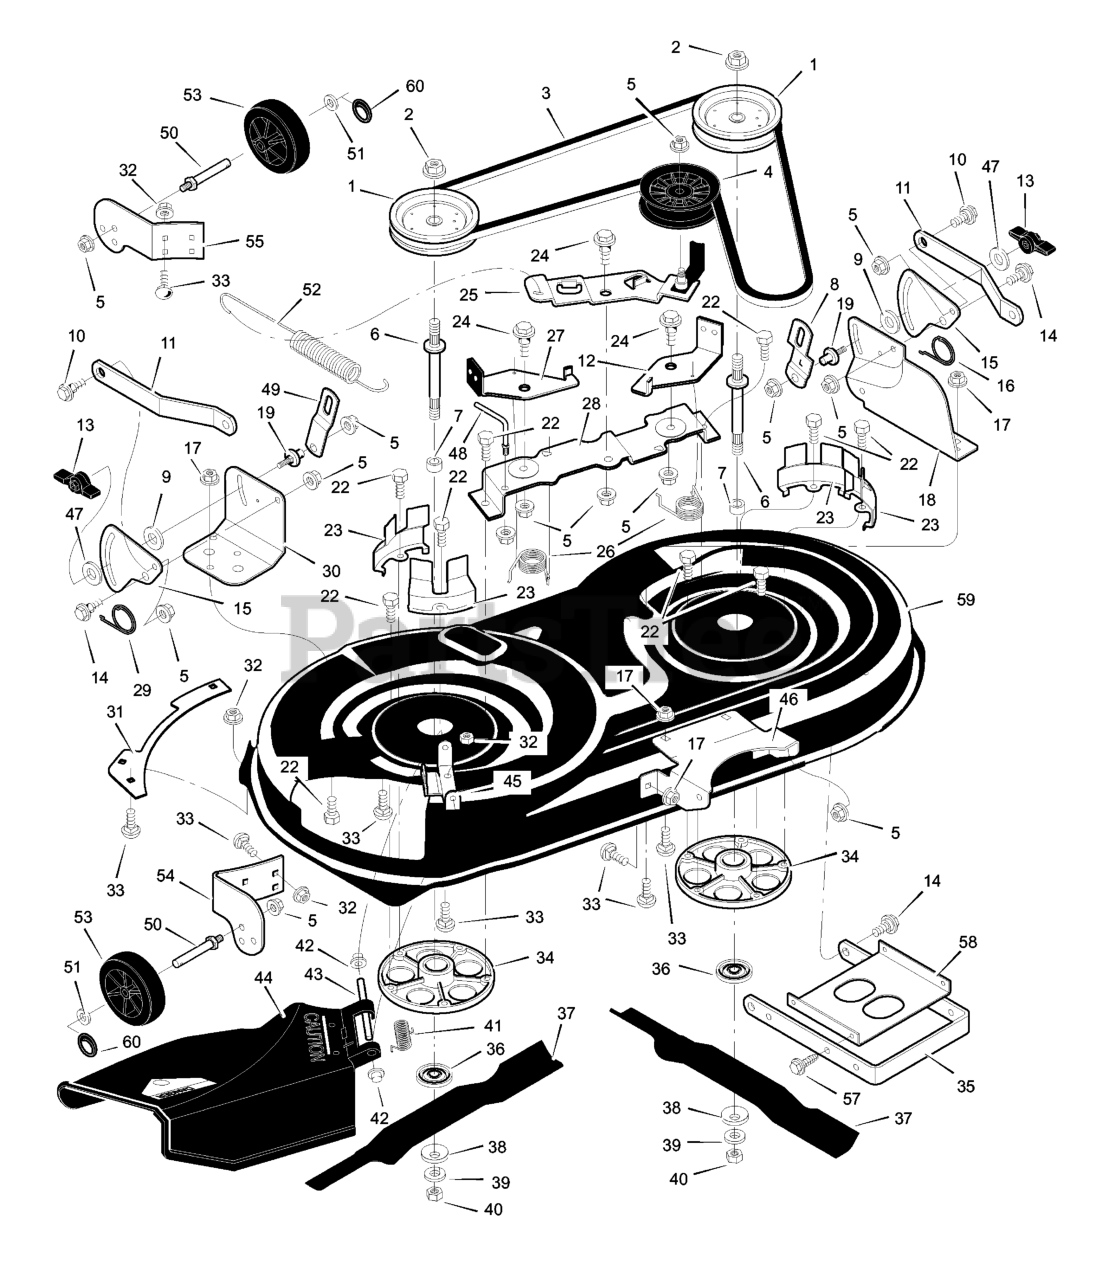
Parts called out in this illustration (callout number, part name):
1	Pulley, Jackshaft
2	Nut, Hex
3	Belt, Mower Drive
4	Pulley, Idler
5	Nut, Flange
6	Jackshaft
8	Link, Left Lift
9	Pad, Friction
10	Bolt, Shoulder
11	Bracket, Suspension
12	Pad Assembly, Left Brake
13	Knob
14	Bolt, Shoulder
15	Plate, Suspension
17	Nut, Flange
18	Bracket, Suspension
19	Pin, Hanger
22	Bolt
23	Cover, Pulley
24	Bolt, Shoulder
25	Arm, Idler
27	Pad Assembly, Right Brake
28	Bracket, Brake
30	Bracket, Suspension
32	Nut, Flange
33	Bolt, Carriage
34	Mandrell Housing
35	Bracket, Suspension
36	Adapter, Blade
42	Cap, Push On
43	ROD, Deflector
44	Deflector Assembly
45	Bracket, Deflector Hinge
46	Bracket, Front Hanger
48	Guide, Belt
49	Link, Right Lift
50	BOLT, Gauge Wheel
52	Spring, Extension
53	Wheel, Gage
54	Bracket, Right Wheel
55	Bracket, Left Wheel
58	Stiffener
59	Housing, Blade, Complete (NO LONGER AVAILABLE)
59	Housing, Blade (Housing Only)
60	Ring, Locking
